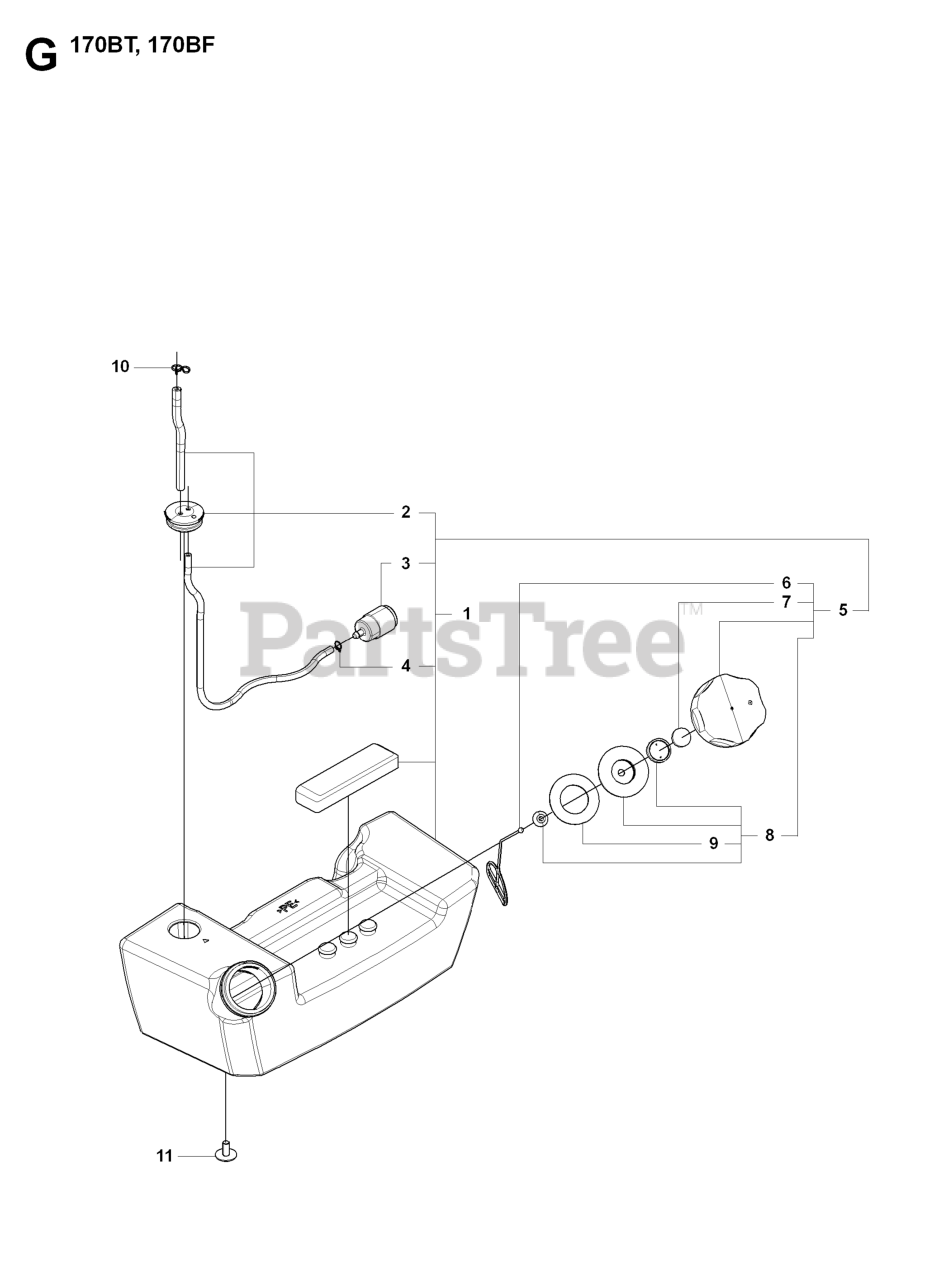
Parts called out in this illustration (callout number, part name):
1	TANK-A
1	TANK
2	RP_PIPE COMPLETE
3	NUT
5	ASSY FUEL CAP
